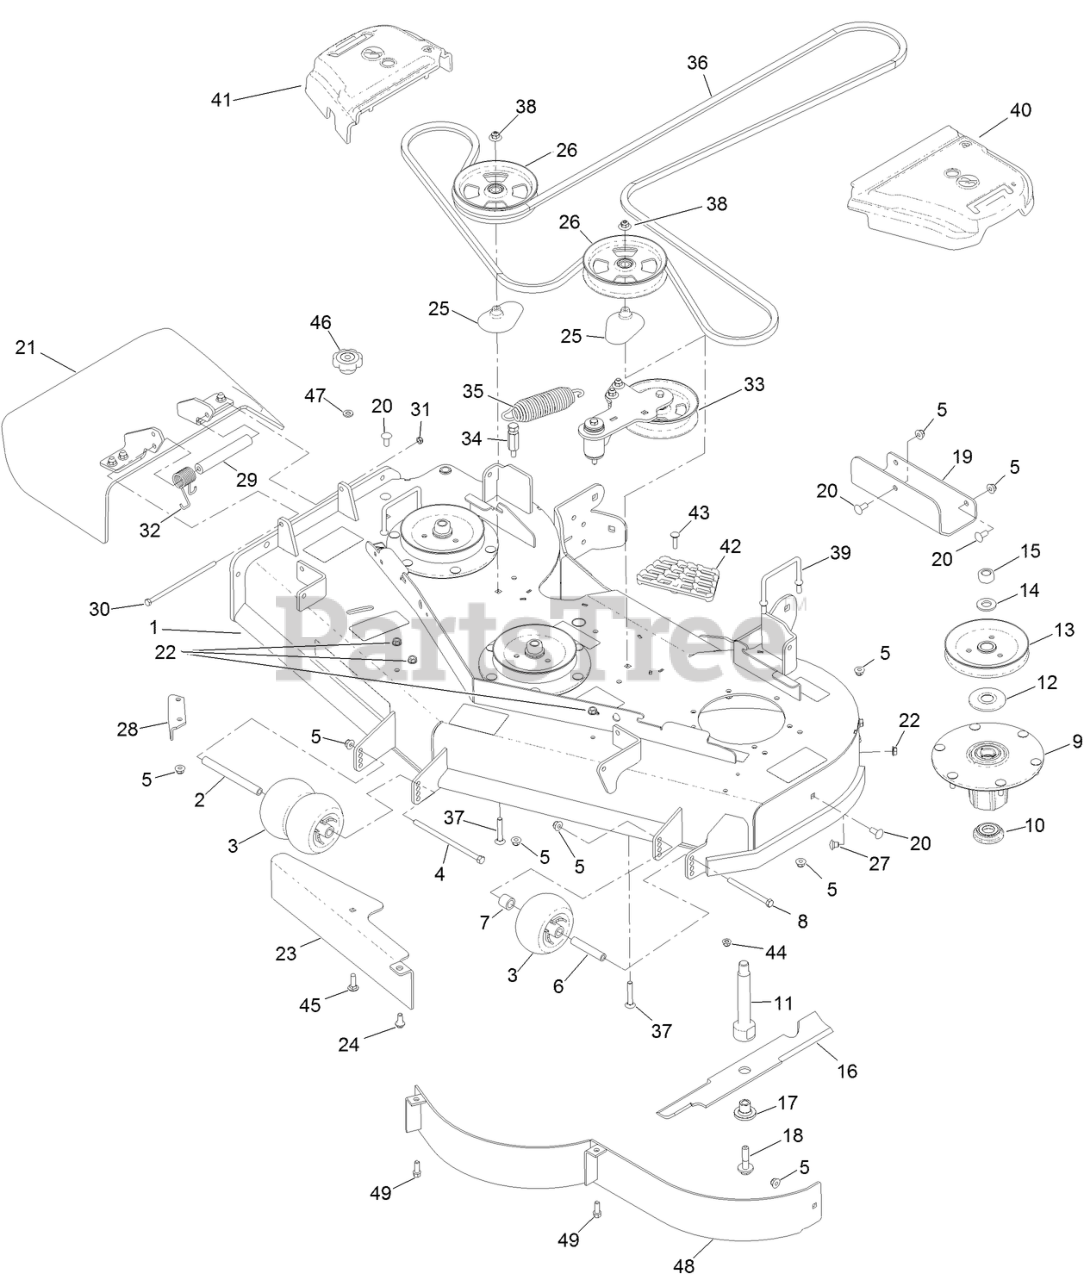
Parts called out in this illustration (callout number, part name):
1	DECK DECAL ASM
2	SPACER-WHEEL
3	ROLLER-SCALP, ANTI
4	SCREW-HH
5	NUT-HF, NI
6	TUBE-SPANNER
7	TUBE-SPACER
8	SCREW-HH
9	SPINDLE ASM
10	GUARD-BOTTOM
11	SHAFT-SPINDLE
12	GUARD-BEARING, TOP
13	SHEAVE-BLADE DRIVE 6.50
14	WASHER
15	NUT-HEX
16	BLADE-FLOW, HIGH
17	BUSHING-HEX
18	SCREW-SEMS
19	PLATE-SKID
20	SCREW-CARR
21	RUBBER DEFLECTOR ASM
22	NUT-HHF, WHIZ
23	PLATE-BAFFLE, FORMED
24	BOLT-SHOULDER
25	SPACER-PULLEY
26	PULLEY-IDLER, FLAT
27	SCREW-CARR
28	BAFFLE-DISCHARGE
29	SPACER
30	SCREW-HH
31	NUT-LOCK, NI
32	SPRING-TORSION
33	IDLER ARM ASM
34	ANCHOR-SPRING, TALL
35	SPRING-EXTENSION
36	BELT-V
37	BOLT-CARR, SHORT NECK
38	NUT-FLANGE, NI
39	WIREFORM-COVER
40	COVER-BELT, LH
41	COVER-BELT, RH
42	STEP-DECK
43	SCREW-CARR
44	NUT-HF, NI
45	BOLT-CARR
47	WASHER-HARDENED
48	BAFFLE ASM
